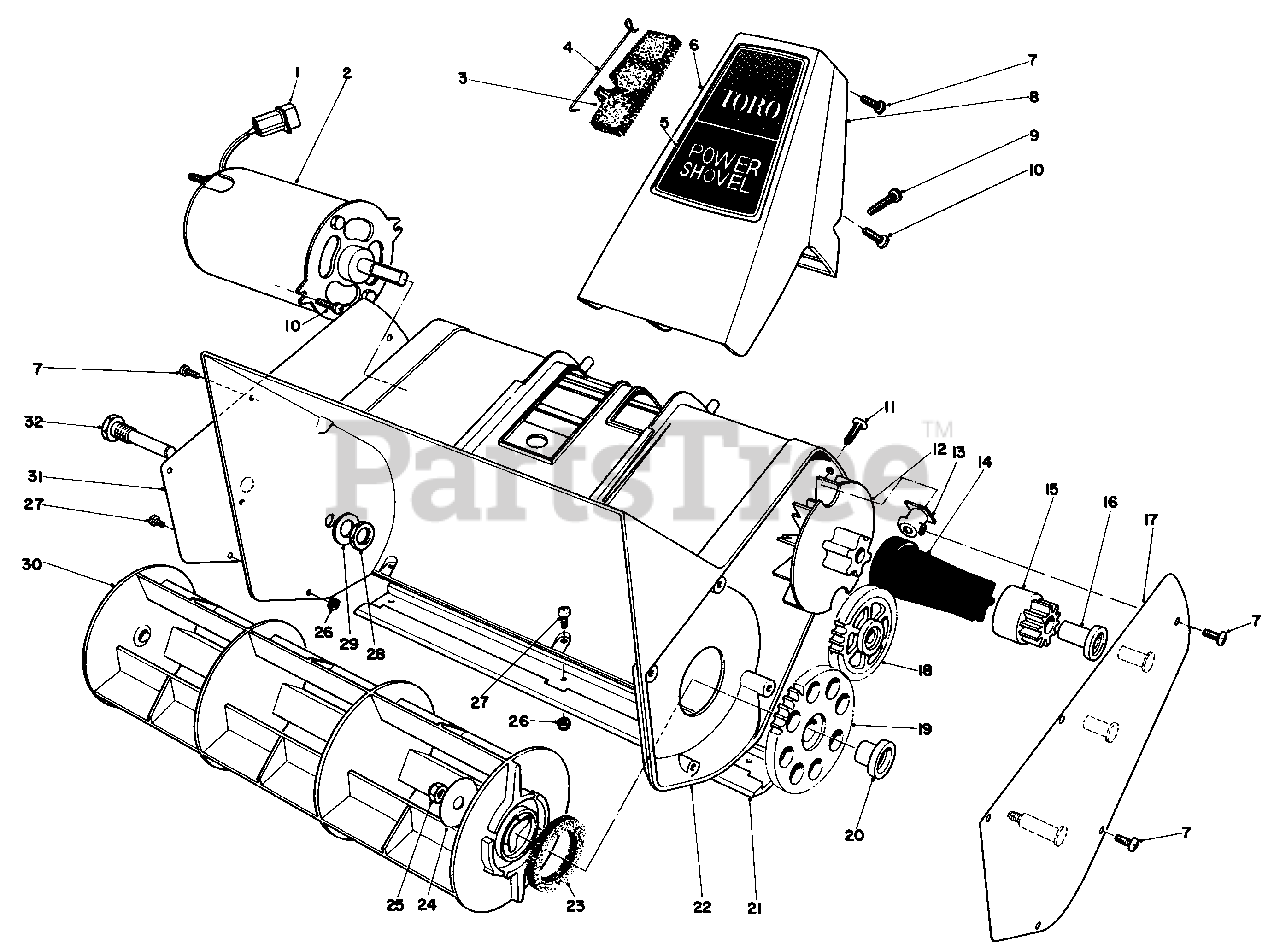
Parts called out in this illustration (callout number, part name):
1	Pin-Housing
2	Motor
3	Filter-Foam
4	Retainer-Filters
5	Decal-Handle Support
6	Handle Support-Front
7	Screw-Pan Head
8	Handle Support-Back
9	Screw-Pan Head
10	Screw-Pan Head
11	Fastener
13	Block-Mounting
14	Coupling-Drive
15	Drive Gear (Incl. Ref. #16)
16	Bushing-Drive Gear
17	Gear Carrier
18	Idler Gear Assembly
19	Rotor Gear Assembly (Incl. Ref. #20)
20	Bushing-Rotor
21	Scraper
23	Washer-Felt
24	Washer-Rotor
25	Locknut-Thin
26	Locknut-Thin
27	Screw-Pan Head
29	Flat Washer
31	Cover, Right Side
32	Pin-Rotor
